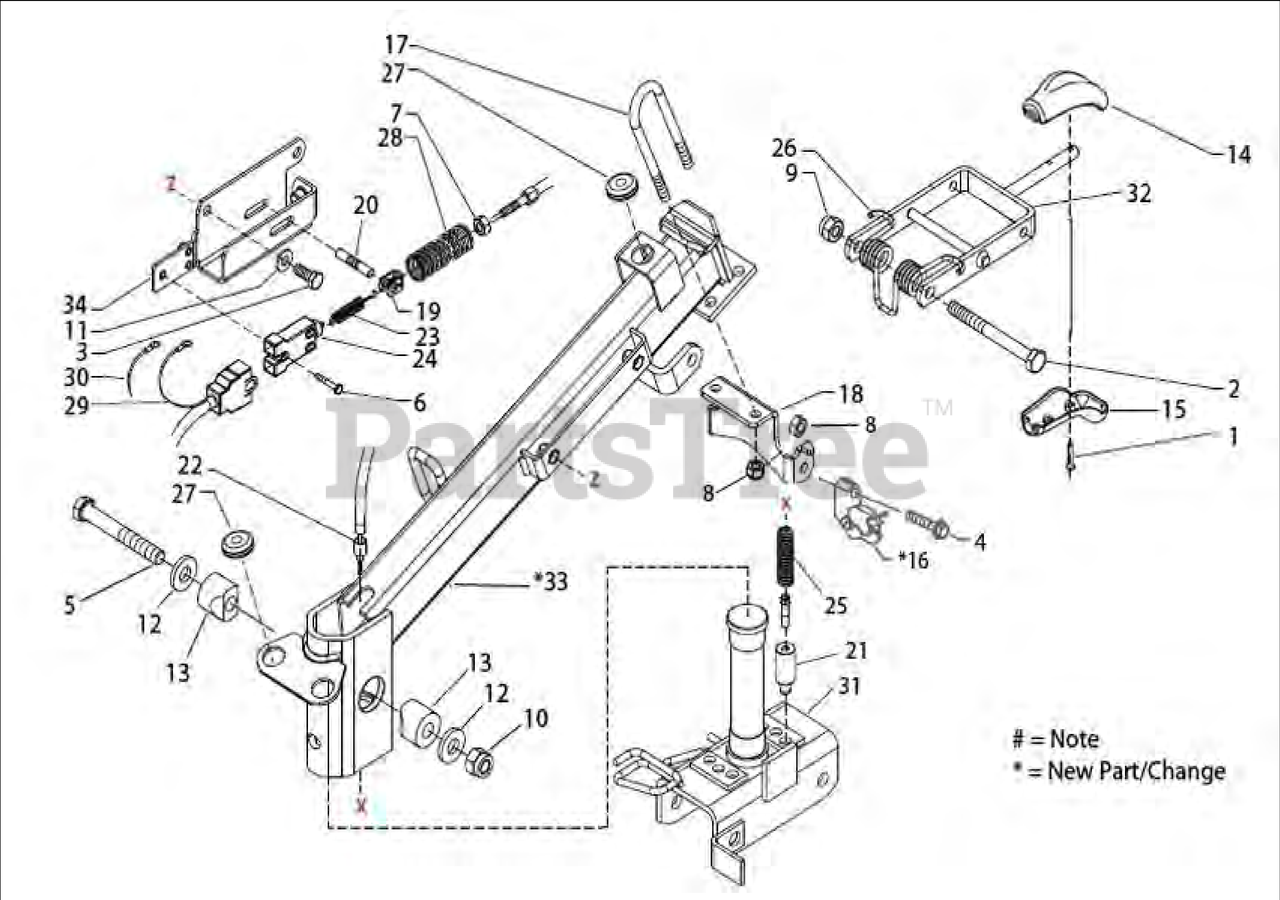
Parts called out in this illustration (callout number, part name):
1	SCREW, M3.5X25
2	CAP SCREW, M10X110 UNI 5737-8G
3	CAP SCREW, M8 X20 UNI 5739-8G
4	CAP SCREW, M8X35 DIN 6921
5	CAP SCREW, M12X80 UNI5737-8G
6	SCREW, M4X25
7	NUT, M8
8	NUT, SELFLOCKING, M8
9	NUT, LOCK STANDARD, M10
10	NUT, LOCK DEFORMED, M12
11	WASHER, SUPER, M8
12	WASHER, SUPER, M12
13	WEDGE
14	HANDLE UPPER (BLACK)
15	HANDLE LOWER (BLACK)
16	SUPPORT, CONTROL ROD W/SPRING
16	Spring not available as a spare part
17	U-BOLT
18	SUPPORT BRACKET, CONTROL ROD
19	MOTOR STOP FORK
20	MOTOR STOP PIN
22	SHEATH END
23	SPRING, INTERLOCK SWITCH
24	INTERLOCK SAFETY SWITCH
25	SPRING, STEERING COLUMN
26	SPRING, HANDLEBAR RELEASE
27	SUPPORT, BODY CAP
28	CHECK SPRING, MOTOR STOP
29	WIRE HARNESS, MOTOR STOP
30	GROUND WIRE
31	STEERING COUPLER
32	LEVER, HANDLEBAR
33	STEERING COLUMN
34	SUPPORT, ENGINE STOP
